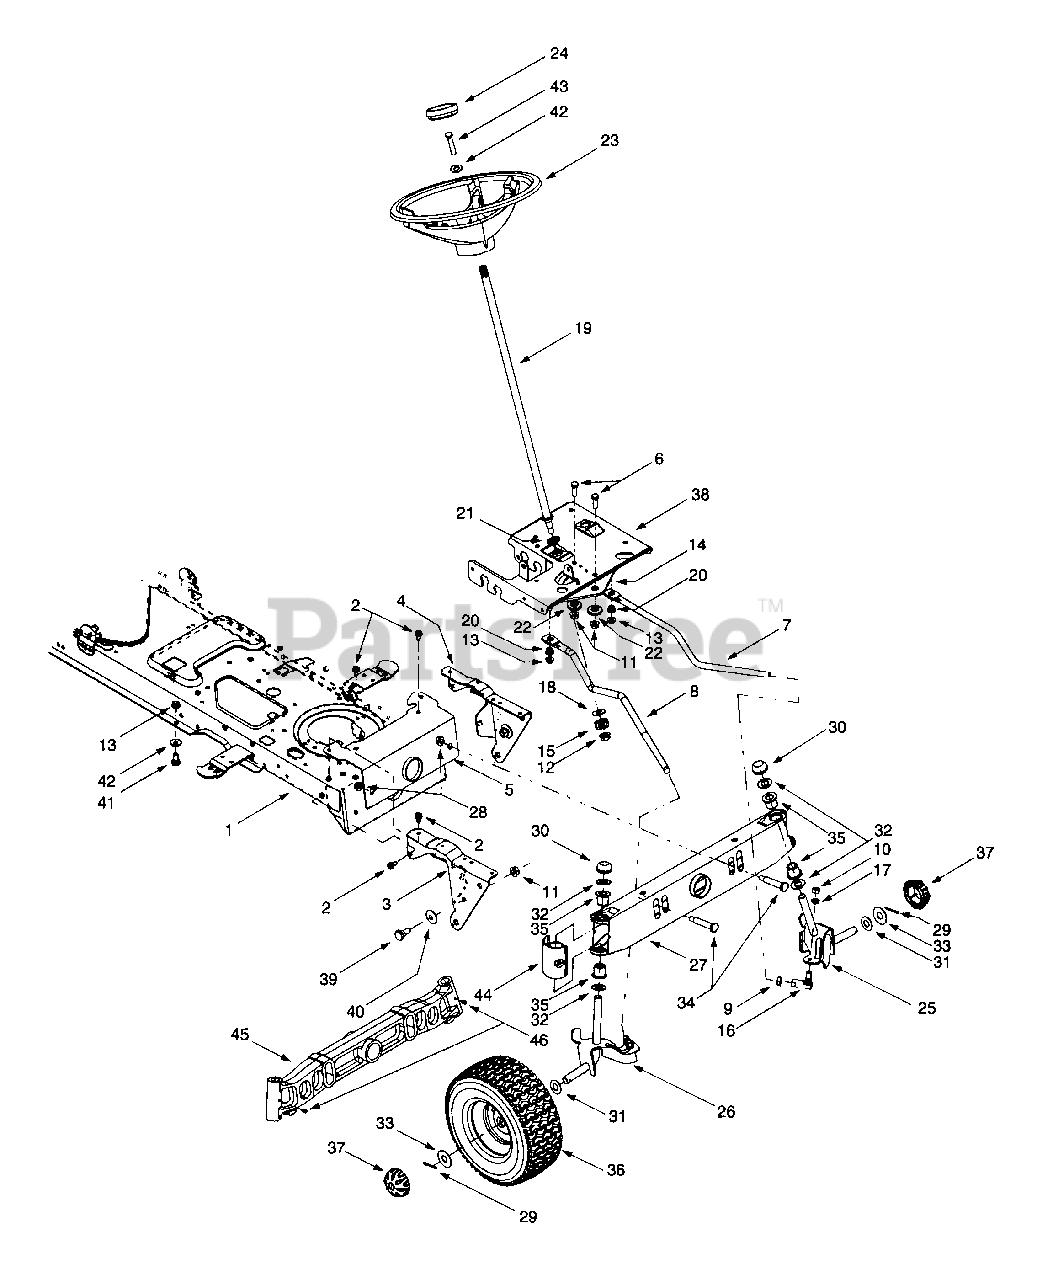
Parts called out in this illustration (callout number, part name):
6	Hex Cap Screw, 3/8-16 x 1 (Grade 5)
7	LH Drag Link
8	RH Drag Link
9	Jam Nut, 7/16-20 (Grade 2)
10	Hex Nut, 3/8-24 (Grade 2)
11	Flange Lock Nut, 3/8-16
12	Flange Lock Nut, 7/16-20
13	Flange Lock Nut, 5/16-18
14	Steering Gear, 11/90 Ratio
15	Steering Pinion Gear
16	Ball Joint, 7/16-20
17	Lock Washer, 3/8
18	Flat Washer, .51 x 1.12 x .06
19	Steering Shaft, .625 OD x 24.4
20	Plastic Bushing,.38 ID
21	Hex Flange Bearing, 5/8
22	Shoulder Spacer, .38 ID
23	Steering Wheel
24	Steering Wheel Cap
25	LH Axle Assembly, .625 Diameter
26	RH Axle Assembly, .625 Diameter
28	Flange Lock Nut,3/8-16
29	Cotter Pin
30	Push Cap, .625
31	Flat Washer, .64 x 1.0 x .12
32	Flat Washer, .64 x 1.24 x .06
33	Flat Washer, .635 x 1.589 x .06
34	Shoulder Screw, .5 x 2.2, 3/8-16
35	Flange Bearing, .632 ID x.937 OD
37	Hub Cap
39	Shoulder Screw, 3/8-16
40	Bell Washer, .39 x 1.13 x .062
41	Shoulder Screw, .435 x .178, 5/16 x .56
42	Bell Washer, .34 x .872
43	Hex Bolt, 5/16-18 X 1
44	Pivot Bar End Cap
45	Cast Iron Pivot Bar
46	Lube Fitting, 3/16
